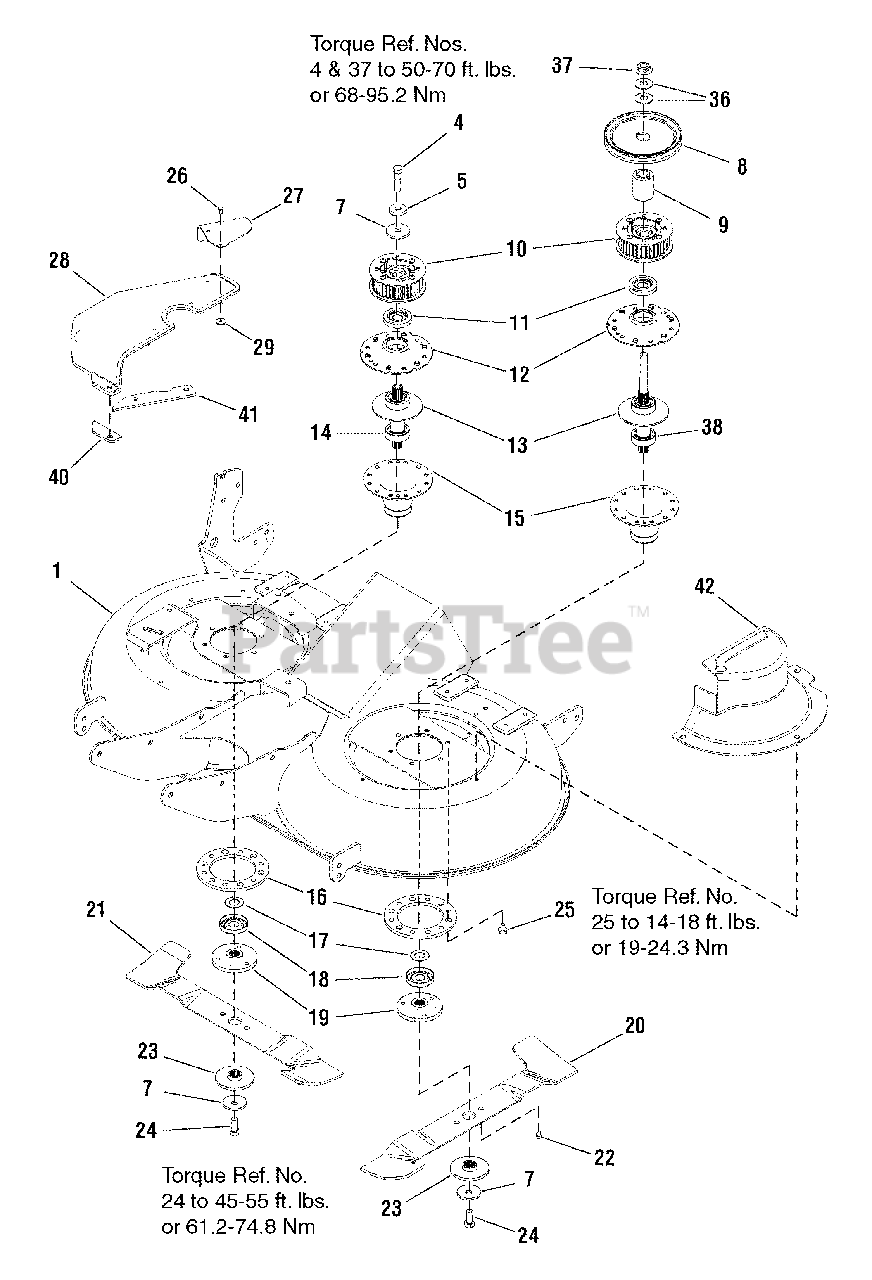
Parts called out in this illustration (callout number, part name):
1	HOUSING ASSEMBLY, 40" Red
3	SCREW, Hex Washer Head Taptite 5/16-18 x 3/4
4	CAPSCREW, Hex Head 7/16-14 x 2-3/4 G8
5	WASHER, 7/16
7	WASHER, Spring
10	SPROCKET & FLANGE ASSEMBLY, Rivets/Screws 40"
11	SHIELD, Bearing, Mower Arbor Uppoer Heat Treated
12	HOUSING, Arbor Top
13	GASKET, Foam
14	ARBOR SHAFT & BEARINGS ASSEMBLY, 40"
15	HOUSING & FITTING ASSEMBLY, Lower
16	ADAPTER, Arbor
17	WASHER, Shim
18	SHIELD, Bearing
19	ADAPTER, Blade
20	BLADE, Mower L.H.
21	BLADE, Mower R.H.
22	PIN, Blade
23	WASHER, Spline
24	CAPSCREW, Hex Head 7/16-14 x 2-1/4 G8
25	SCREW, Hex Washer Head Taptite 5/16-18 x 1
26	RIVET, Pop
27	GUARD, Extension
28	COVER, Arbor R.H.
36	WASHER, Bellville .56ID x 1.34 OD x .05T
37	NUT, Hex Flange 9/16-18
38	ARBOR SHAFT & BEARINGS ASSEMBLY, 40"
40	SHIM, Cover L.H.
41	SHIM, Cover R.H.
42	COVER, Arbor L.H.
